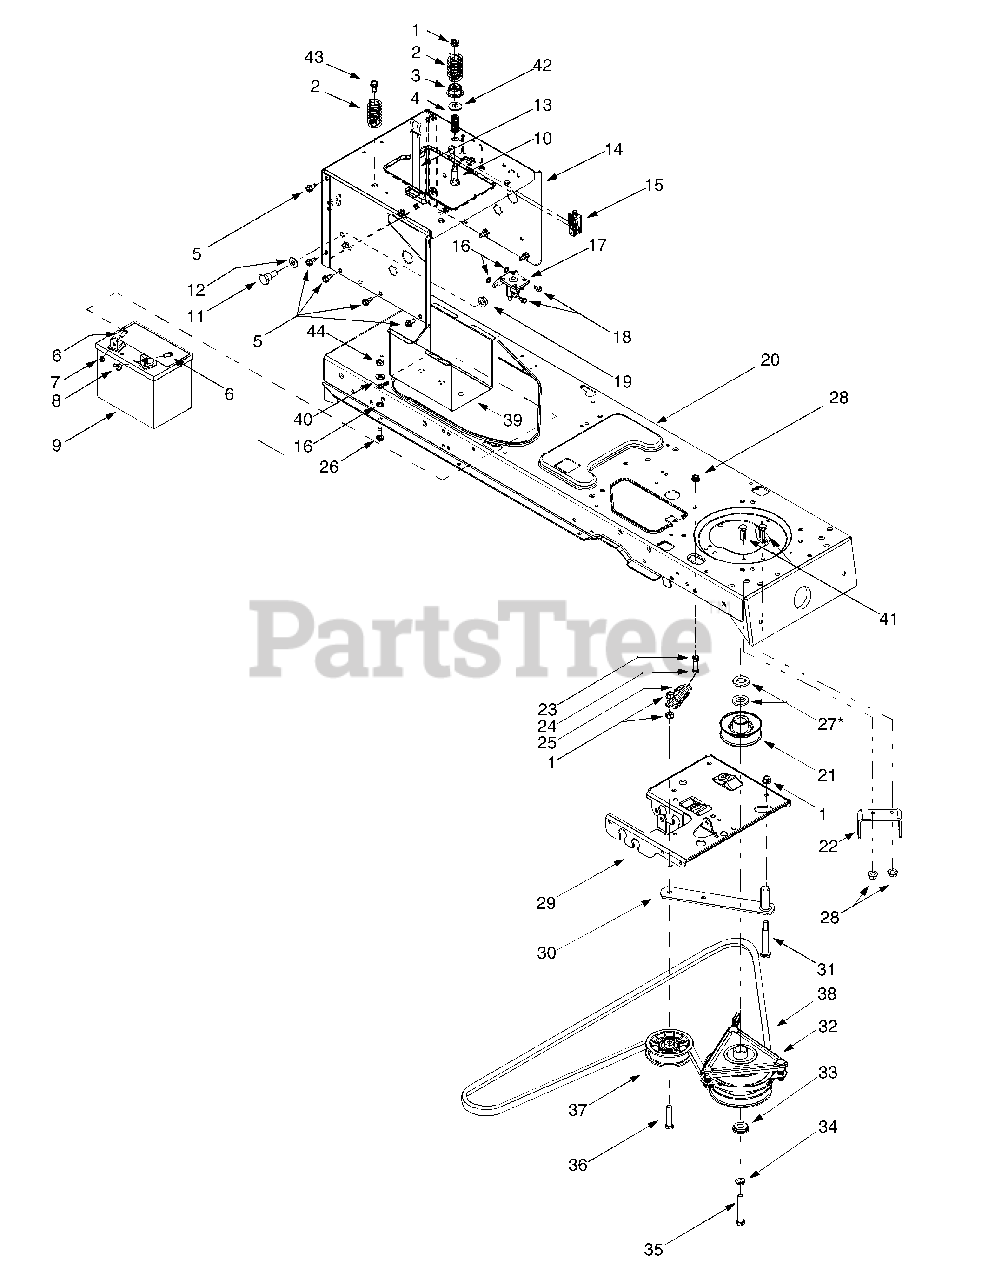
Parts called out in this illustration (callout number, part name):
1	Flange Lock Nut, 3/8-16
2	Compression Spring, 1.318 x 2.37
3	Spacer Cup, 1.5 OD
4	Compression Spring, .66 OD x 1.5
5	Self-tapping Screw, 5/16-18 x .625
6	Hex Cap Screw, 1/4-20 x .62
7	Hex Sems Nut, 1/4-20
8	Wing Nut, 1/4-20
9	12-volt Battery, 270 CCA
10	Shoulder Screw, .5 x 1.25, 3/8-16
11	Shoulder Screw, .625 x .5, 7/16-20
12	Bell Washer, .45 x 1.0 x .062
13	Battery Strap
16	Lock Washer, 1/4
17	Solenoid, 12-Volt, 100 Amp
18	Self-tapping Screw, 1/4-20 x .5
19	Flange Lock Nut, 7/16-20
24	Hex Cap Screw, 5/16-18 x 1.75 (Grade 5)
25	Extension Spring, 1.2 OD x 3.638
26	Self-tapping Screw, 1/4-20 x .750
27	Flat Washer, 1.031 x 1.62 x .095
28	Flange Lock Nut, 5/16-18
29	Steering Support Bracket
32	Electric PTO Clutch
33	Shoulder Spacer, 1.38 x .445 x .36
34	Lock Washer, 7/16
35	Hex Cap Screw, 7/16-20 x 3.25 (Grade 5)
36	Hex Cap Screw, 3/8-16 x 2.25 (Grade 5)
37	Flat Idler Pulley, 3.5 OD
38	PTO Belt (46-inch Decks)
41	Hex Cap Screw, 5/16-18 x .625
42	Bell Washer, .401 x .870 x .063
43	Self-tapping Screw, 5/16-18 x .875
44	Hex Nut, 1/4-20
